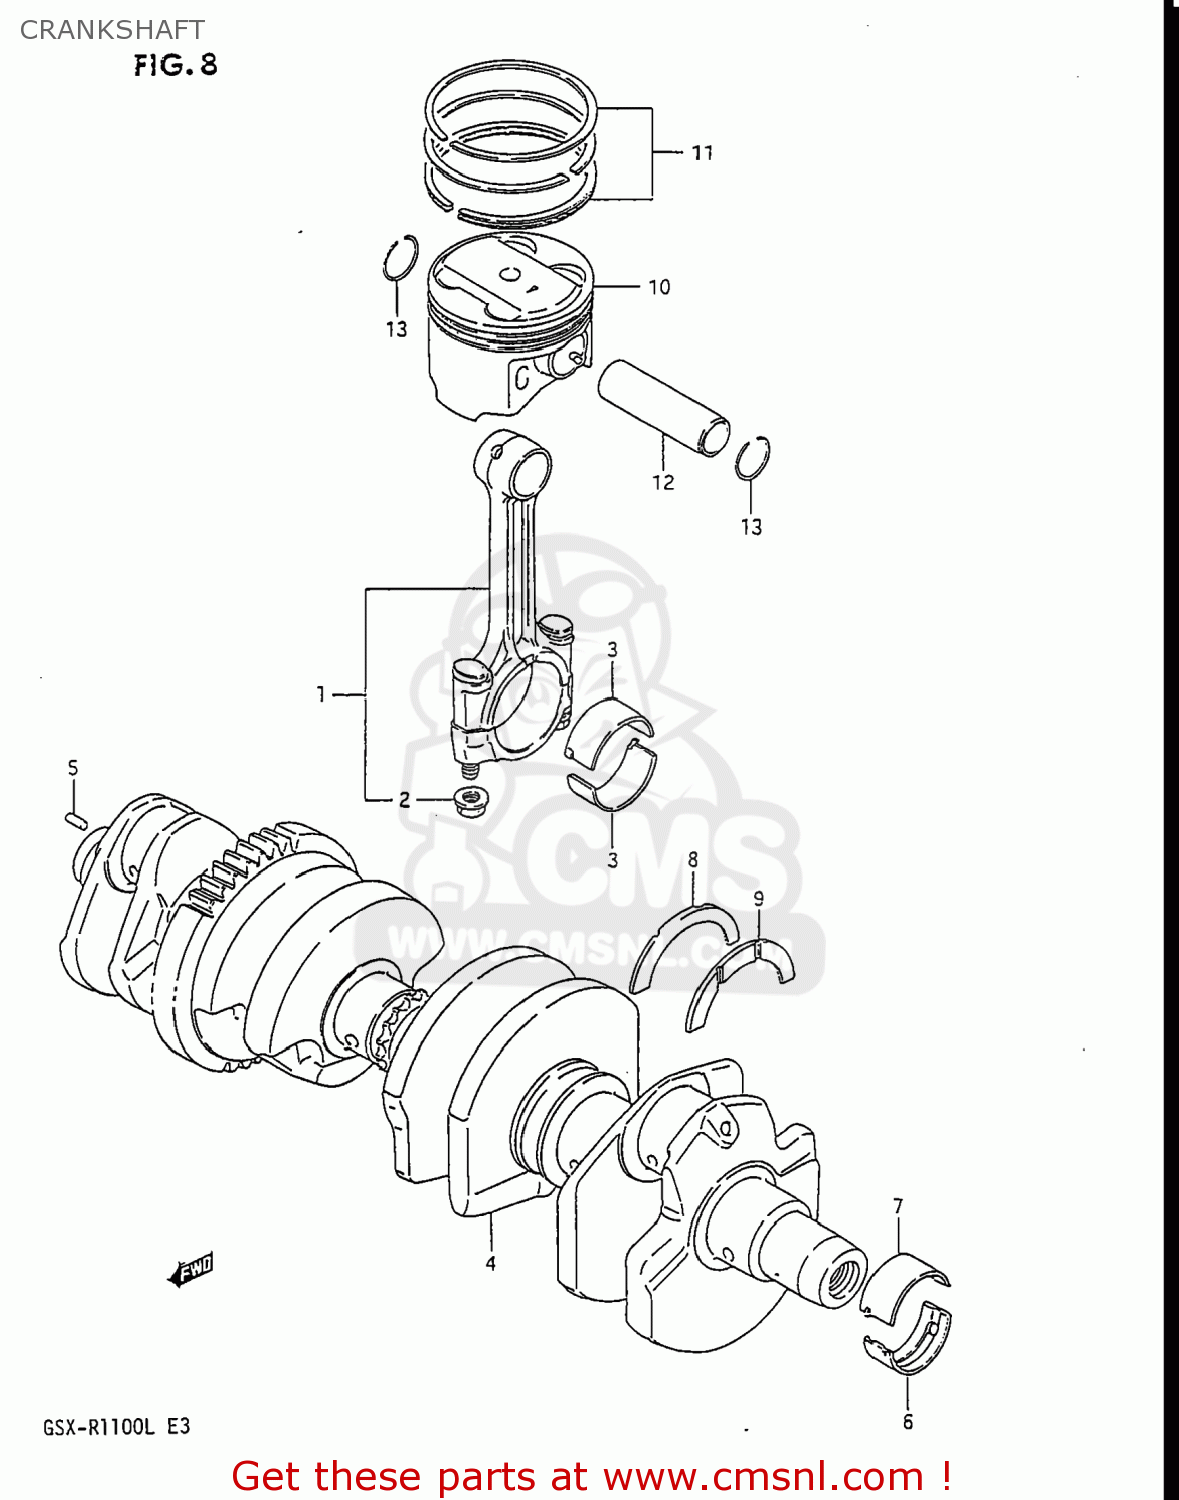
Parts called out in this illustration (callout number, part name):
1	CONNECTING ROD ASSEMBLY
2	NUT
3	BEARING,CRANK PIN
4	CRANKSHAFT
5	PIN
6	BEARING,CRANKSHAFT LWR
7	BEARING,CRANKSHAFT UPR
8	BEARING,CRANK THRUST(GREEN)
9	BEARING,CRANK THRUST(RED)
10	PISTON
11	RING SET,PISTON
12	PIN,PISTON
13	CIRCLIP,PISTON PIN
